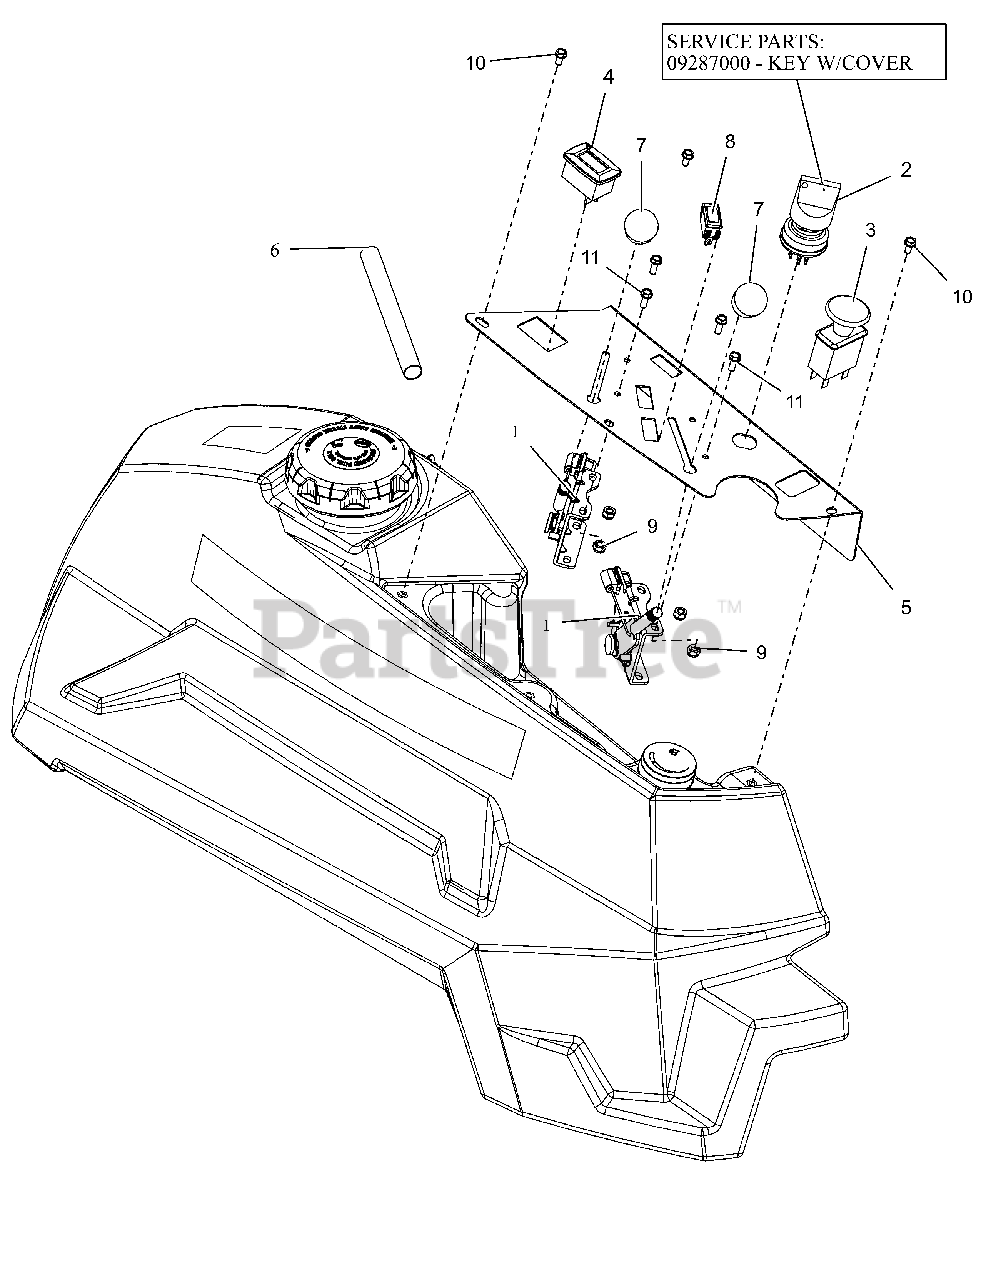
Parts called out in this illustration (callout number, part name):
1	CABLE, PRO-CTRL 43.00"
2	SWITCH, IGNITION
2	KEY, W/ SHIELD
3	SWITCH, CLUTCH
4	METER, HOUR W/MAINTENANCE
5	PT400 CONTROL PANEL - RED
6	SLEEVE, THERMAL 6"
7	KNOB-CONTROL-BLACK .38-16X.50
8	LIGHT,INDICATOR
9	@NUT-LK-NYL 10-24 W/INSRT YWZC
10	SCR-MCH 10-24X.38 HWHSTAINLESS
11	@SCR-MCH 10-24X.50 HWH YWZC
